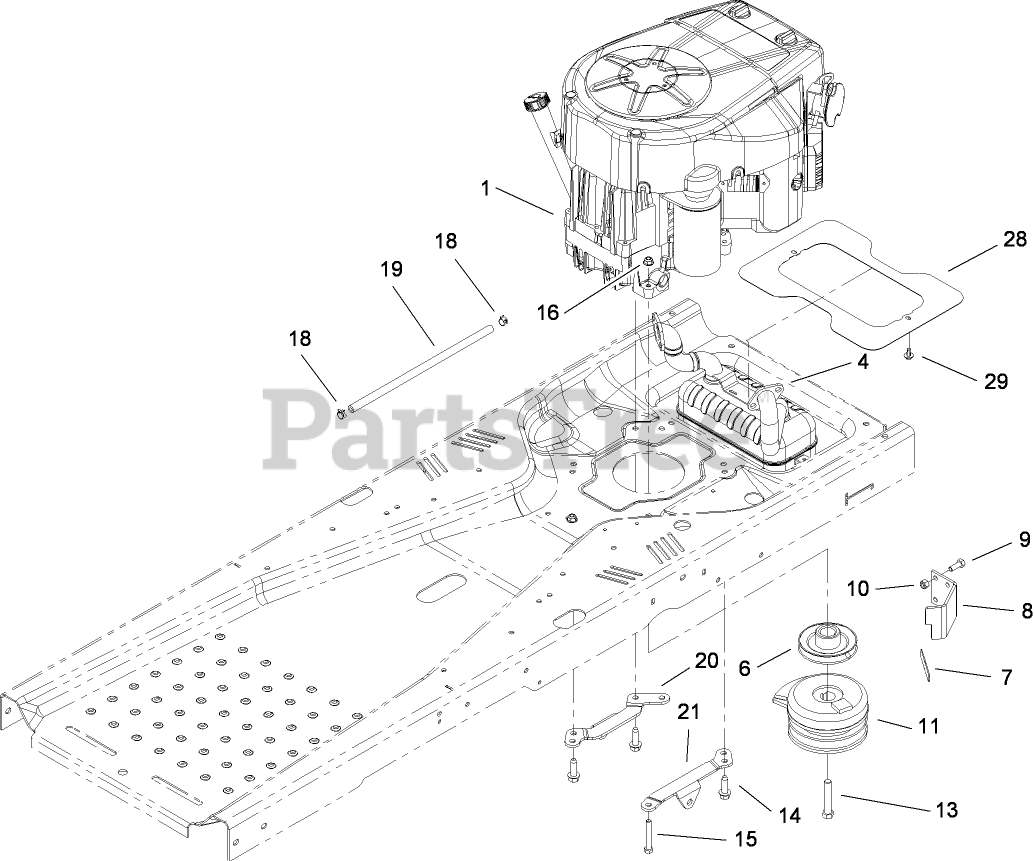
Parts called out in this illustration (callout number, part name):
1	Loose Parts Package
4	MUFFLER-KAWASAKI TWIN
6	PULLEY-ENGINE
7	BUMPER-PAD
8	STOP-CLUTCH
9	SCREW-HH
10	NUT-LOCK, NI
11	CLUTCH-ELECTRIC, PTO
13	SCREW-HH
14	SCREW-THD
15	SCREW-HH
16	NUT-HF, NI
18	CLAMP-HOSE
19	HOSE-FUEL
20	SUPPORT-HYDRO, RH
21	SUPPORT-HYDRO, LH
29	SCREW-HHFTF
